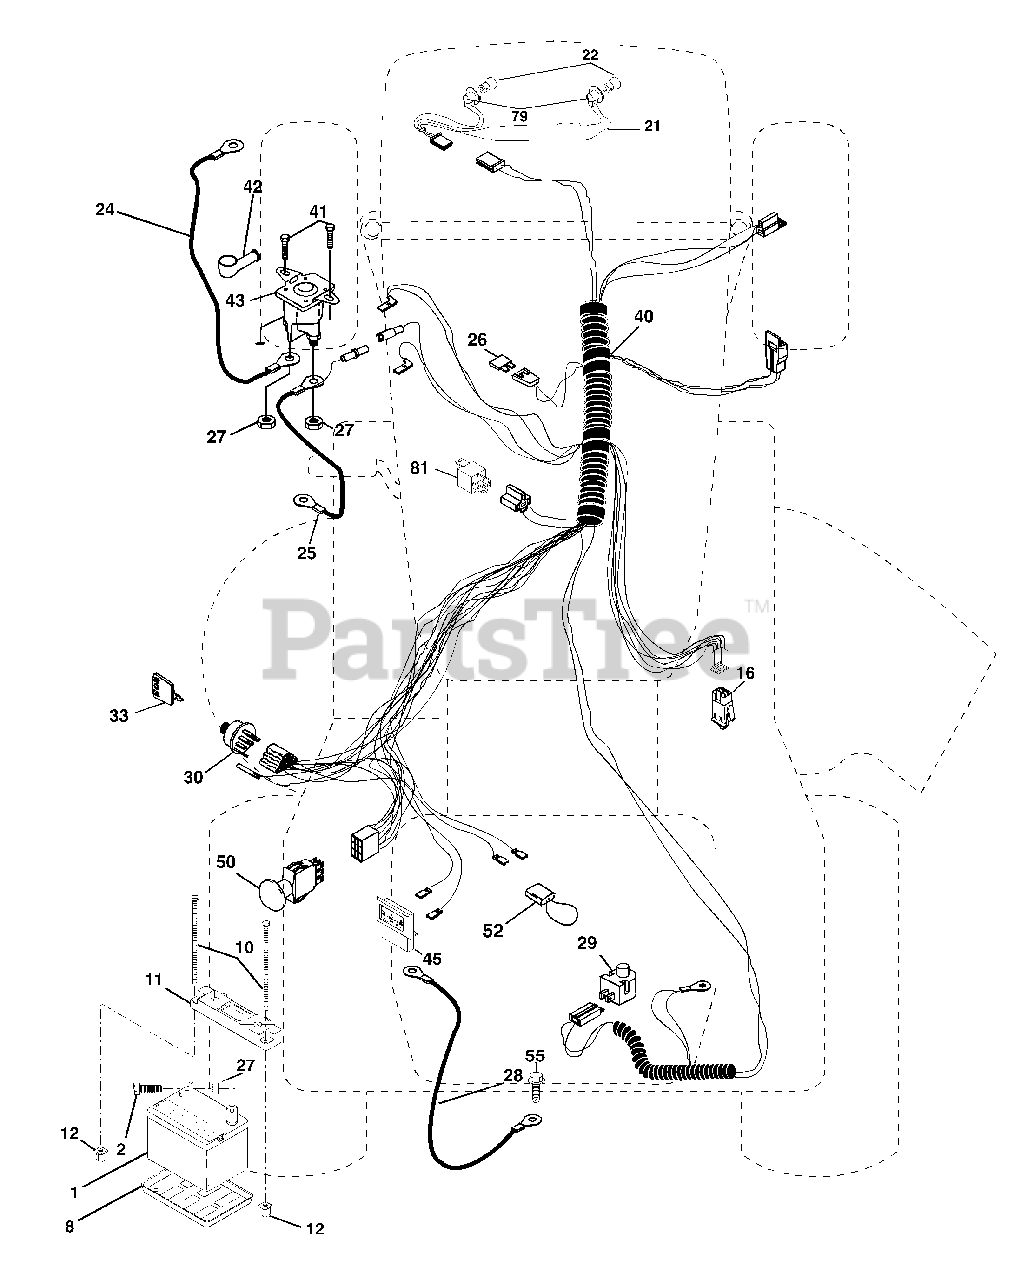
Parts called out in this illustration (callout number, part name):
1	Battery
2	Bolt Hex Hd 1/4-20 UNC X 3/4
8	Tray, Battery
10	Bolt, BTR FRT 1/4-20 x 7.5
11	Hold Down Battery, Front
12	Nut, Push, Nylon
16	Switch Interlock Push-In
21	Harness Asm Light W/Bulbs
22	Bulb Light
24	Cable Battery
25	Cable Batterywire
26	Fuse
27	Nut Keps Hex 1/4-20 Unc
28	Cable Ground
29	Switch Plunger Normal OP Olive
30	Switch Ign 4 pos w/lights
33	Key Ign
40	Harness Ign.
41	Bolt Blk Fin Hex 1/4-20 x 1/2
42	Cover Terminal Red
43	Solenoid
45	Ammeter Rectangular
50	Switch, PTO
52	Protection Wire Loop
55	Screw Thdrol 5/16-18 x 1/2
79	Socket Asm Bulb Twistlock
81	Relay Asm
